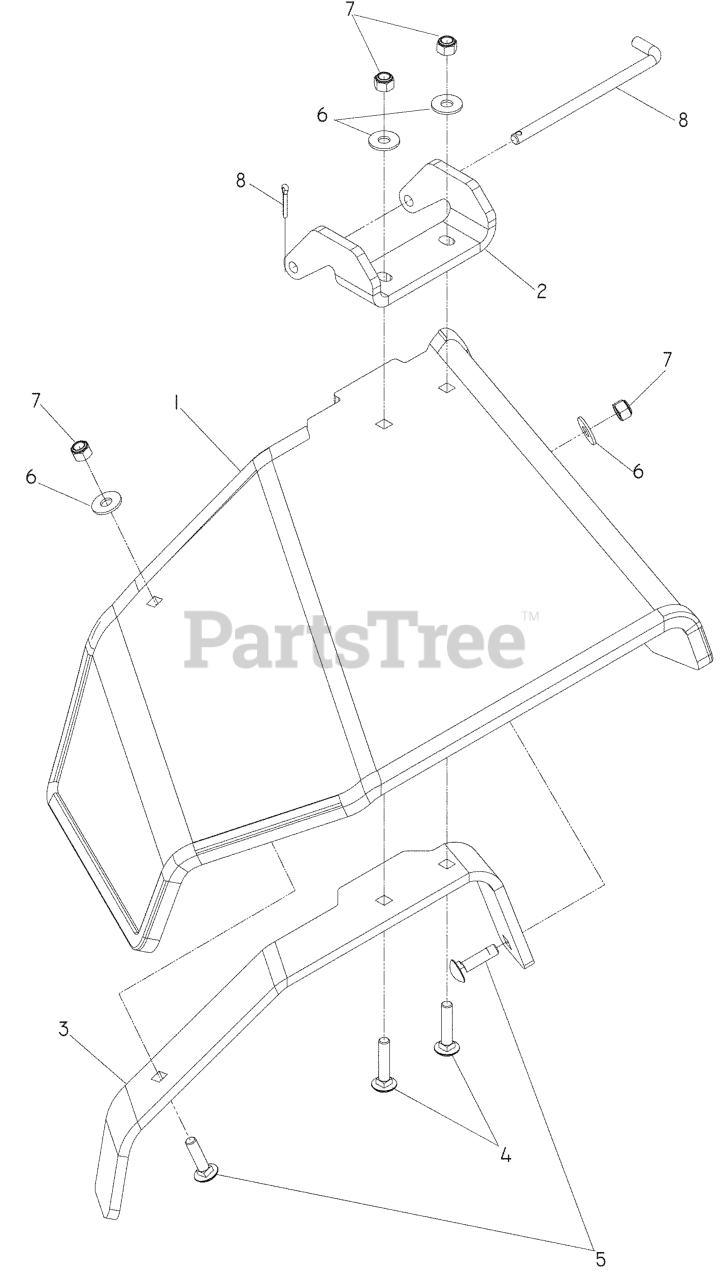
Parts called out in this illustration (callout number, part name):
1	CHUTE, RUBBER DISCHARGE 52/61"
2	PIVOT BRACKET - RUBBER CHUTE
3	BRACKET, REINF-CHUTE
4	RHSNB 5/16-18 X 1-1/2 GR 5 ZD
5	BOLT, CARRIAGE 5/16X1-1/4
6	WASHER 5/16 FLAT
7	NUT 5/16 NYLOC
8	PIN, CHUTE PIVOT
